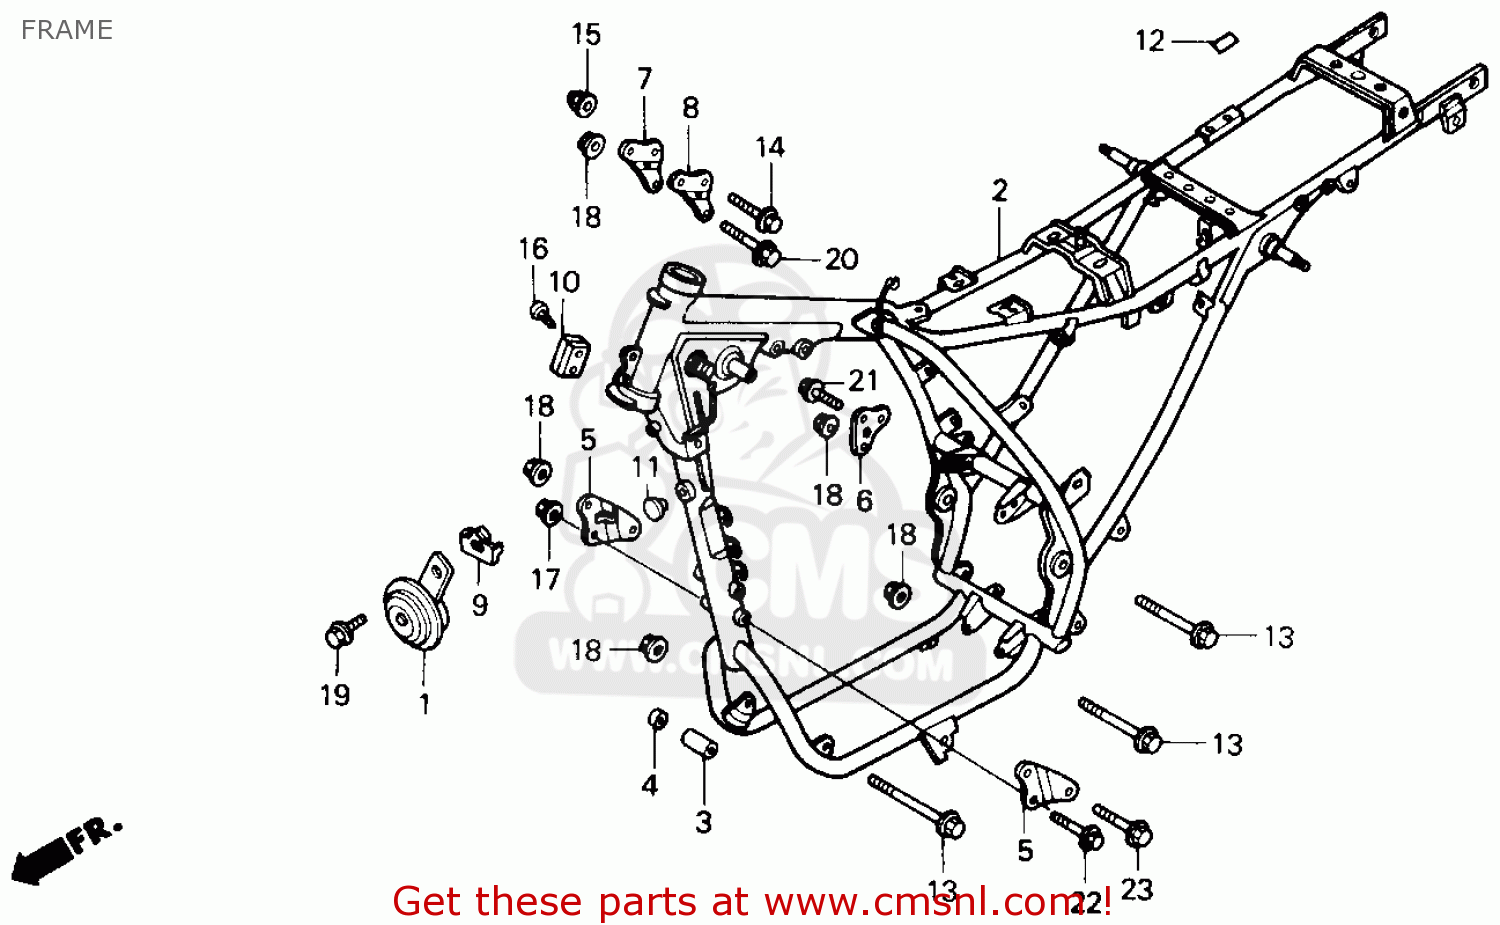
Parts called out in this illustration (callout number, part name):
1	HORN COMP.,HIGH
2	FRAME *NH1*
3	COLLAR,L FR.ENG H
4	COLLAR,R FR.ENG.H
5	STAY, R. FR. ENG HGR
6	PLATE,RR.ENGINE H
7	STAY, R.
8	STAY, L.
9	BRACKET,HORN SETT
10	COVER, FAIRING STAY
11	SEAL, PNL INSIDE (HO
12	LABEL, COLOR (TYPE1)
13	BOLT,FLNG,10X110
14	BOLT.FLANGE 8X57
15	NUT,HEX.CAP
16	SCREW,TAPPING,5X2
19	BOLT,FLANGE,8X16
20	BOLT,FLANGE,10X60
21	BOLT,FLANGE,8X16
22	BOLT,FLANGE,DR 8X
23	BOLT,FLANGE,10X70
